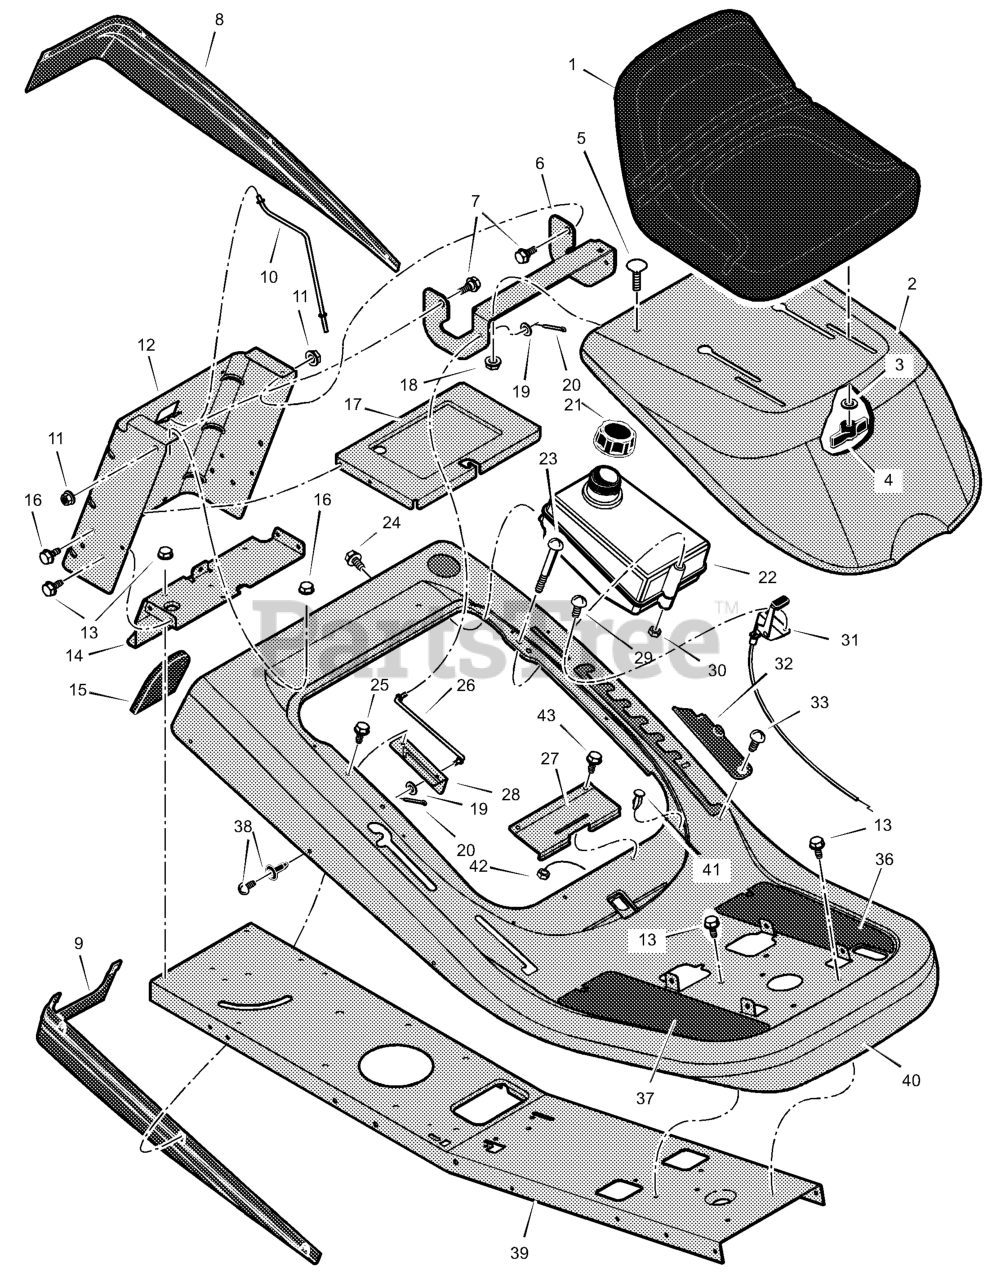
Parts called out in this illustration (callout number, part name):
3	Washer
4	Bolt, Wing
5	Bolt, Carriage
6	Bracket, Hinge
7	Bolt, Shoulder
8	Trim, Gray Left
9	Trim, Gray Right
10	Rod, Battery
11	Nut, Flange
12	Plate, Rear
14	Plate, Hitch
15	Cover, Gray
17	TRAY, Battery
18	Nut, Flange
19	Washer
20	Pin, Cotter
21	Cap, Fuel Tank
22	Tank, Fuel
26	Rod, Hood Prop
27	Spring, Seat Deck
28	Bracket, Prop Rod
30	Nut, NY-Lock
31	Control, Throttle
32	Cover, Gray Detent
33	Bolt, Shoulder
36	Footmat, Left
37	Footmat, Right
38	Fastener, Trim
40	Deck, Seat
41	Bumper
42	Nut
43	Screw
